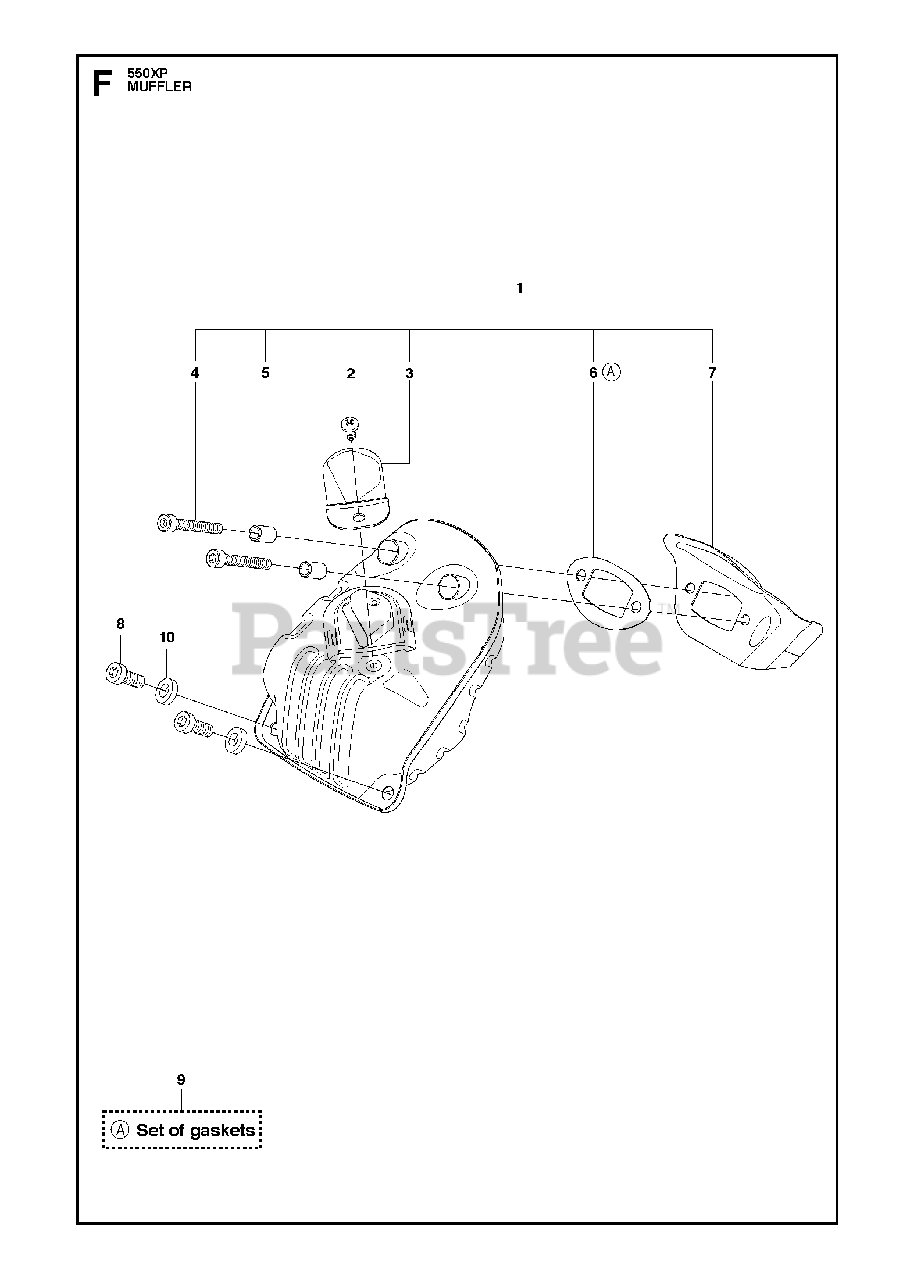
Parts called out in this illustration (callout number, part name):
1	MUFFLER KIT
2	SCREW
3	SPARK ARRESTER A004 50 CC
4	SCREW
5	SLEEVE
6	GASKET MUFFLER
7	HEAT DEFLECTOR
9	GASKET KIT
